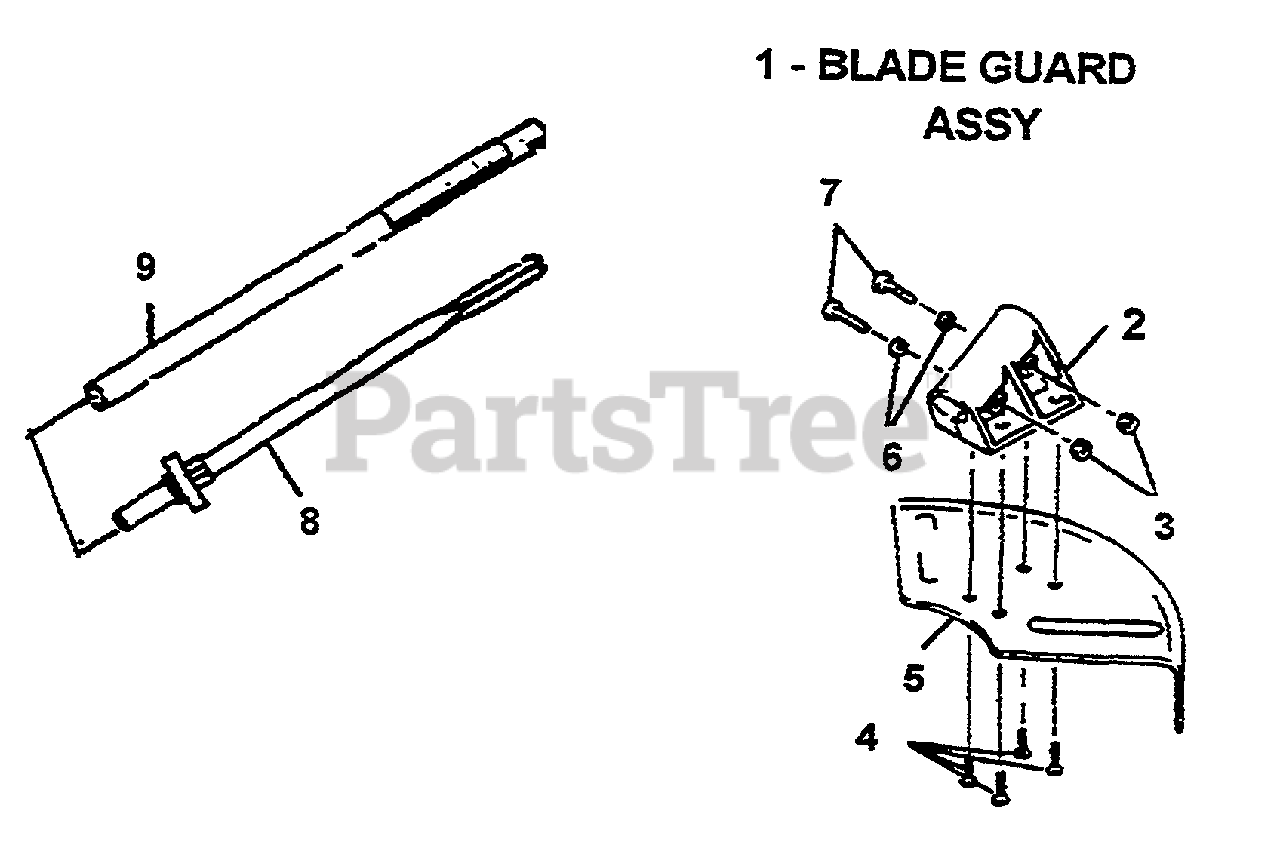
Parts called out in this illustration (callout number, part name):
1	BLADE GUARD ASSY
4	SCREW
5	GUARD
8	FLEX CABLE
9	TUBE ASSY
